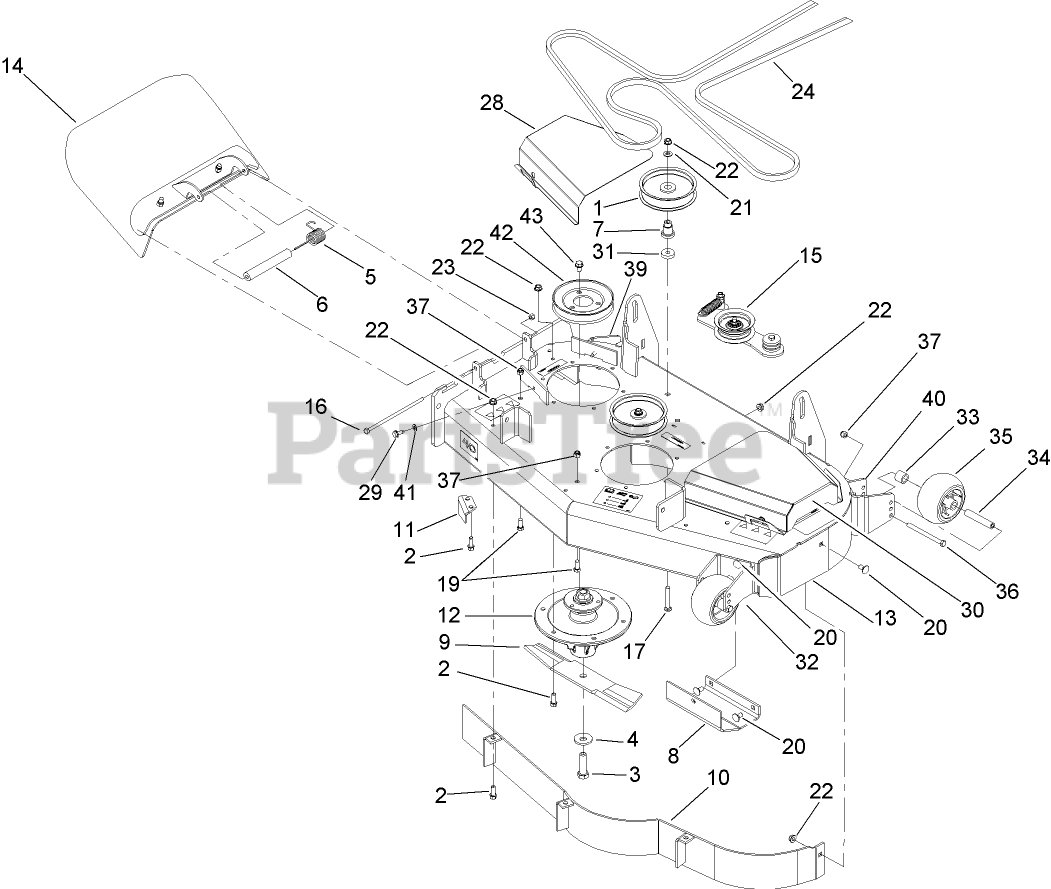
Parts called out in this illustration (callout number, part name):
1	PULLEY-IDLER
2	SCREW-HWH
3	SCREW-BLADE
4	Washer-Blade Bolt, Heavy
5	SPRING-TORSION
6	SPACER
7	MOUNT-PULLEY
9	BLADE-ROTARY, 14 INCH (RECYCLING)
10	BAFFLE ASM
11	BAFFLE-DISCHARGE
12	SPINDLE ASM
13	DECK DECAL ASM
14	DEFLECTOR ASM
15	IDLER ASM
16	SCREW-HH
17	SCREW-CARR
19	SCREW-HH
20	SCREW-CARR
21	WASHER-FLAT
22	NUT-HHF, WHIZ
23	NUT-LOCK, NI
24	BELT-V
28	COVER-RH
29	SCREW-HWHTF
30	COVER-LH
31	Spacer
32	PLATE-SUPPORT, WHEEL
33	TUBE-SPACER
34	TUBE-SPANNER
35	ROLLER-SCALP, ANTI
36	SCREW-HH
37	NUT-LOCK, NI
39	MOUNT-WHEEL, RH
40	MOUNT-WHEEL, LH
41	WASHER-PLAIN
42	PULLEY
43	SCREW-HHFTF
